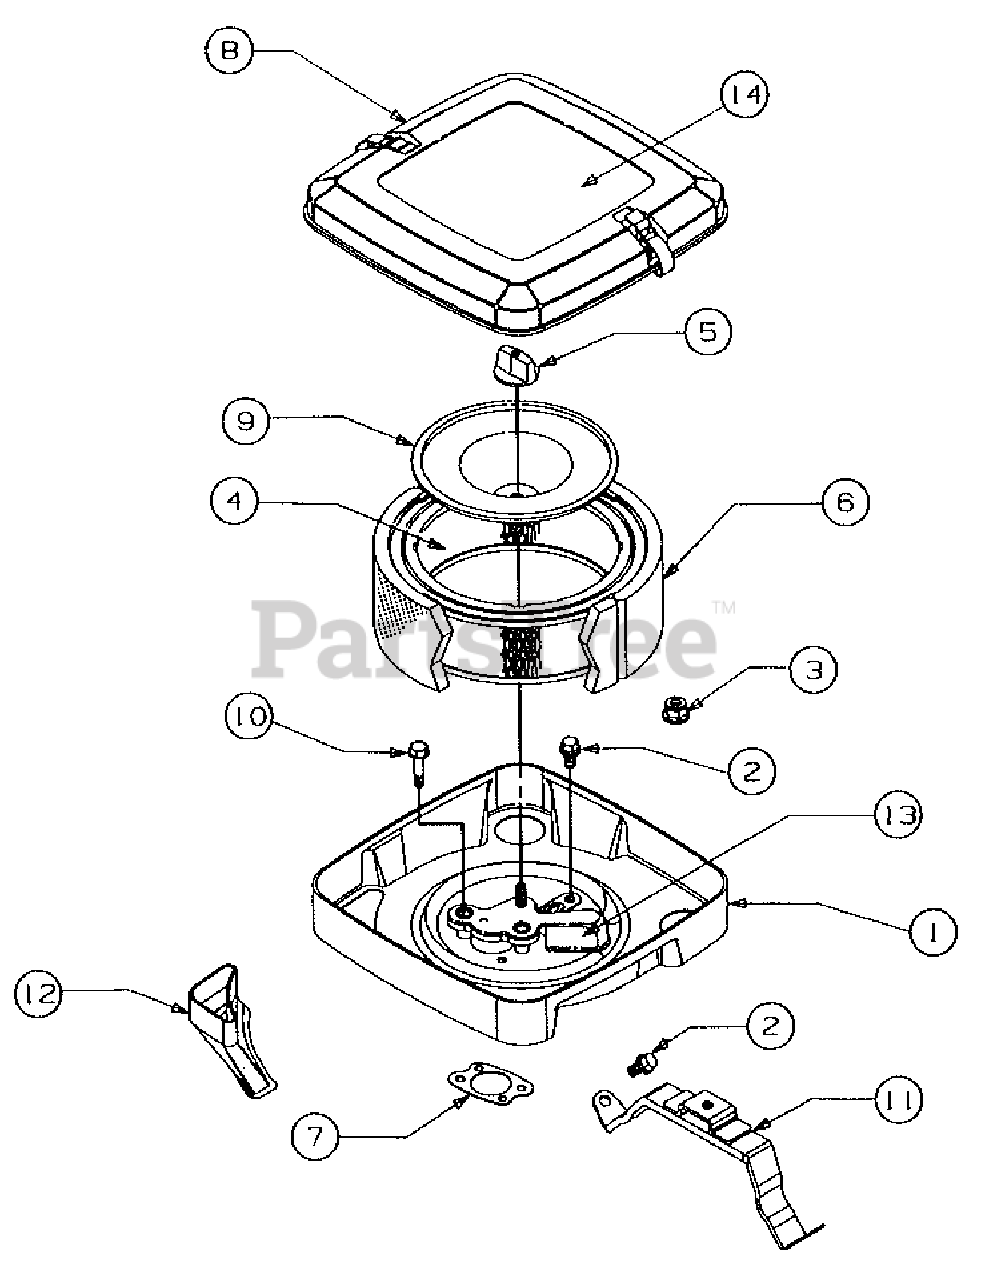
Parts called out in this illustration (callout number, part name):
1	Base, Air Cleaner
2	Screw, Sem
4	Cartridge, Air Filter
5	Knob, Air Cleaner
6	Element, Pre-Cleaner
7	Gasket, Air Cleaner
8	Cover, Air Cleaner
9	Plate, Cartridge
10	Screw, Sem
11	Bracket, Air Cleaner
12	Tube, Air Inlet
13	Shield, Carburetor Air Cleaner
14	Lable, V-Twin Engine
